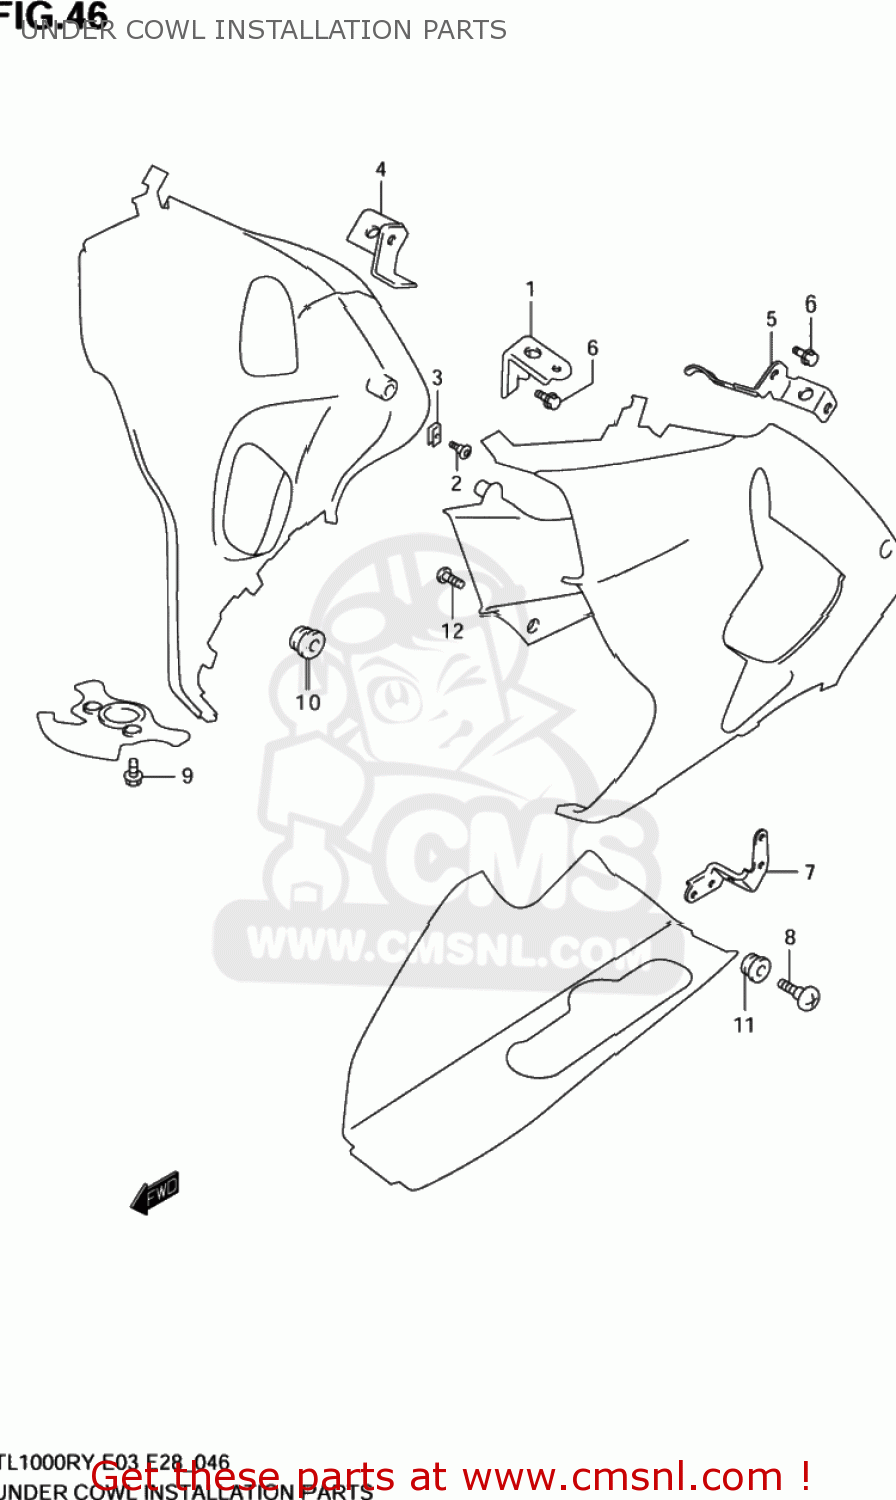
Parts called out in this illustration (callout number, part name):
1	BRACKET,UNDER COWLING UPR
2	SCREW(5X16)
3	NUT,COWL
4	BRACKET,UNDER COWLING SIDE,R
5	BRACKET,UNDER COWLING,SIDE
6	BOLT
7	BRACKET,UNDER COWLING,LOWER
8	SCREW(6X20)
9	BOLT
10	CUSHION
11	CUSHION
12	SCREW
